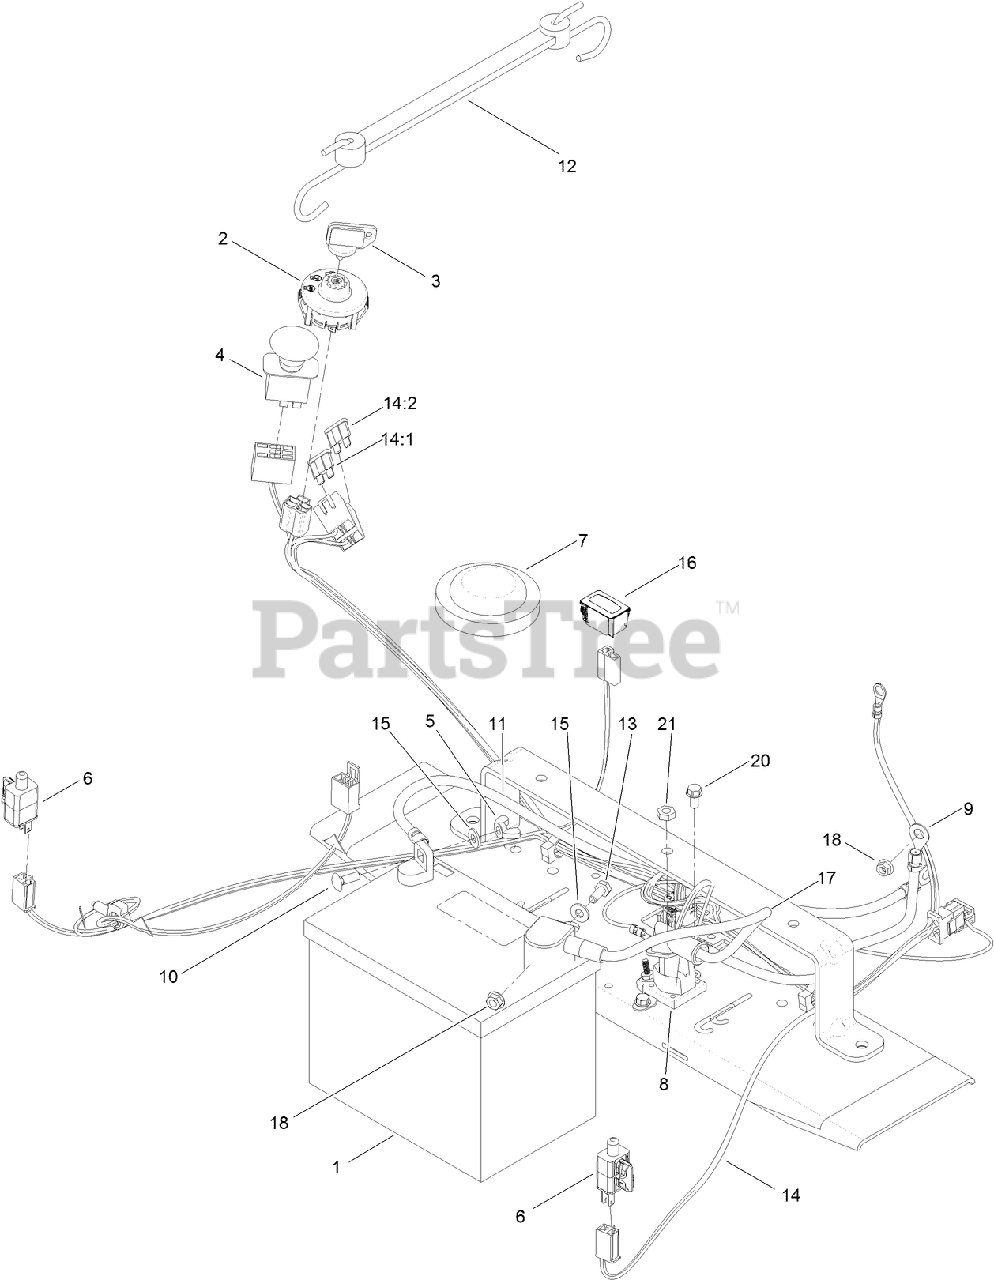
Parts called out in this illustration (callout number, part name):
1	BATTERY
3	KEY-IGNITION
4	SWITCH-PTO
5	NUT-WING
6	SWITCH
7	SWITCH-SEAT
8	SOLENOID
9	CABLE-BATTERY, POSITIVE
10	BOLT-CARR
11	CABLE-BATTERY, BLACK
12	HOLDDOWN-BATTERY
13	SCREW-HH
14:1	FUSE-BLADE, 30 AMP
14:2	FUSE-BLADE, 25 AMP
15	WASHER-FLAT
16	HOURMETER
17	CABLE-BATTERY, RED
18	NUT-HF
20	SCREW-HWH
21	NUT-JAM
